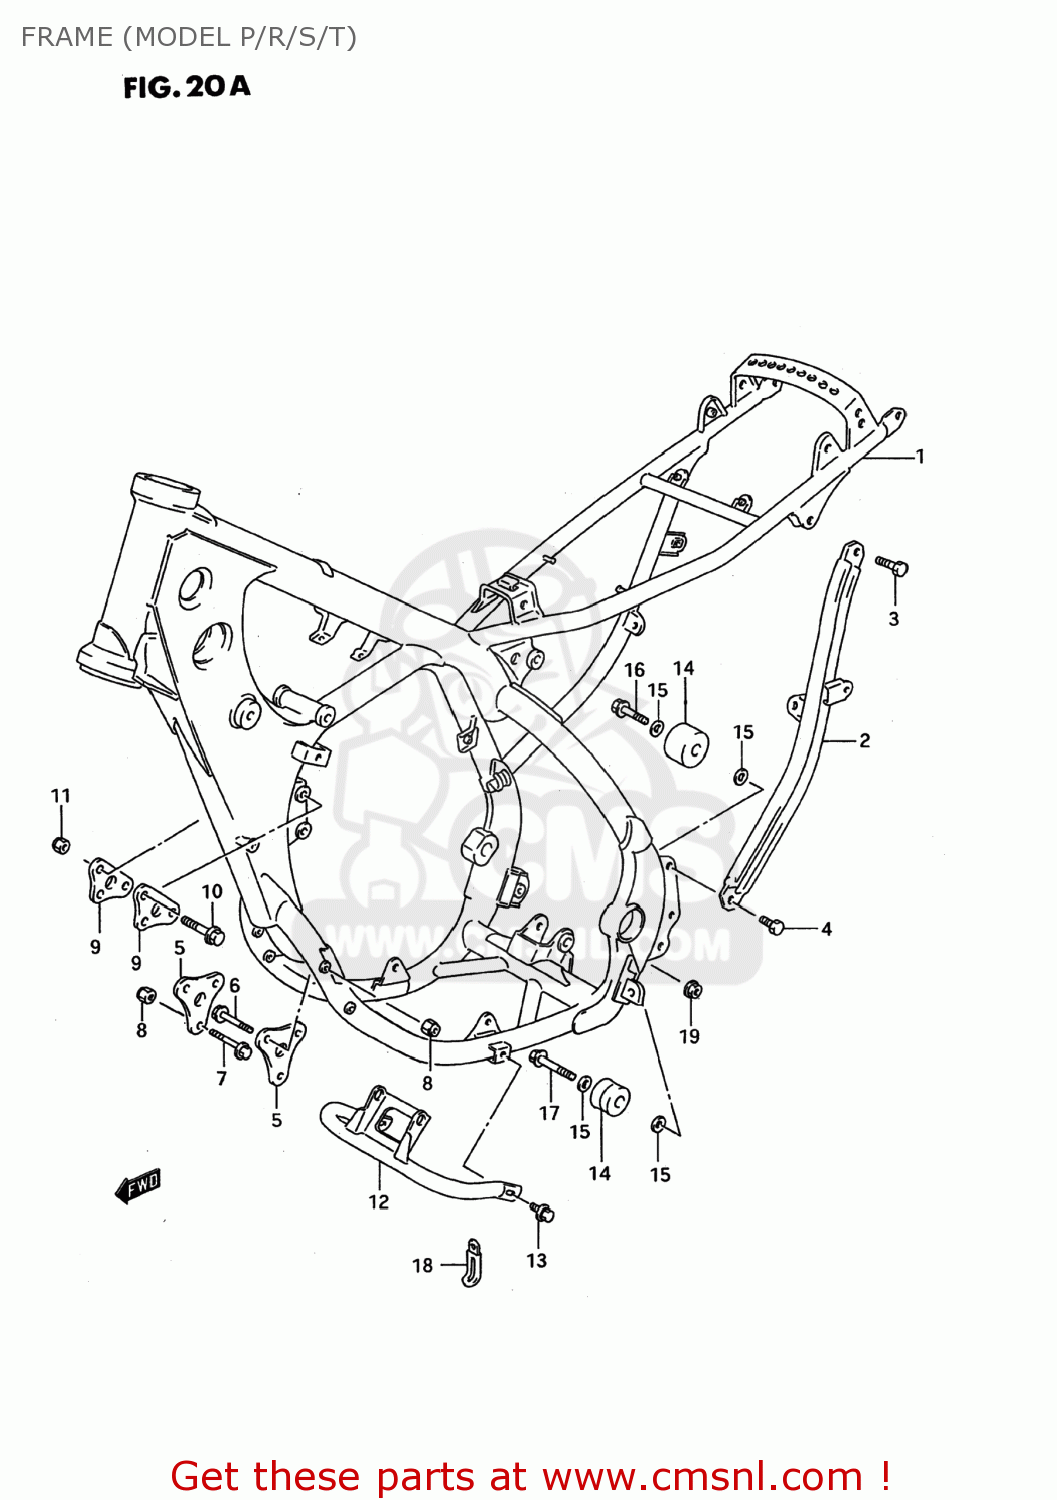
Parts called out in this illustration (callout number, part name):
1	FRAME COMP
2	TUBE,FRAME SIDE,L
3	BOLT
4	BOLT
5	PLATE,ENG MTG FR
6	BOLT 8X55
7	BOLT M8X65
8	NUT
9	PLATE,ENGINE MOUNT UPR
10	BOLT(8X45)
11	NUT
12	PROTECTOR,ENGINE
13	BOLT(8X14)
14	ROLLER,CHAIN
15	WASHER
16	BOLT(8X41)
17	BOLT(8X45)
18	CLAMP(L:65)
19	NUT
